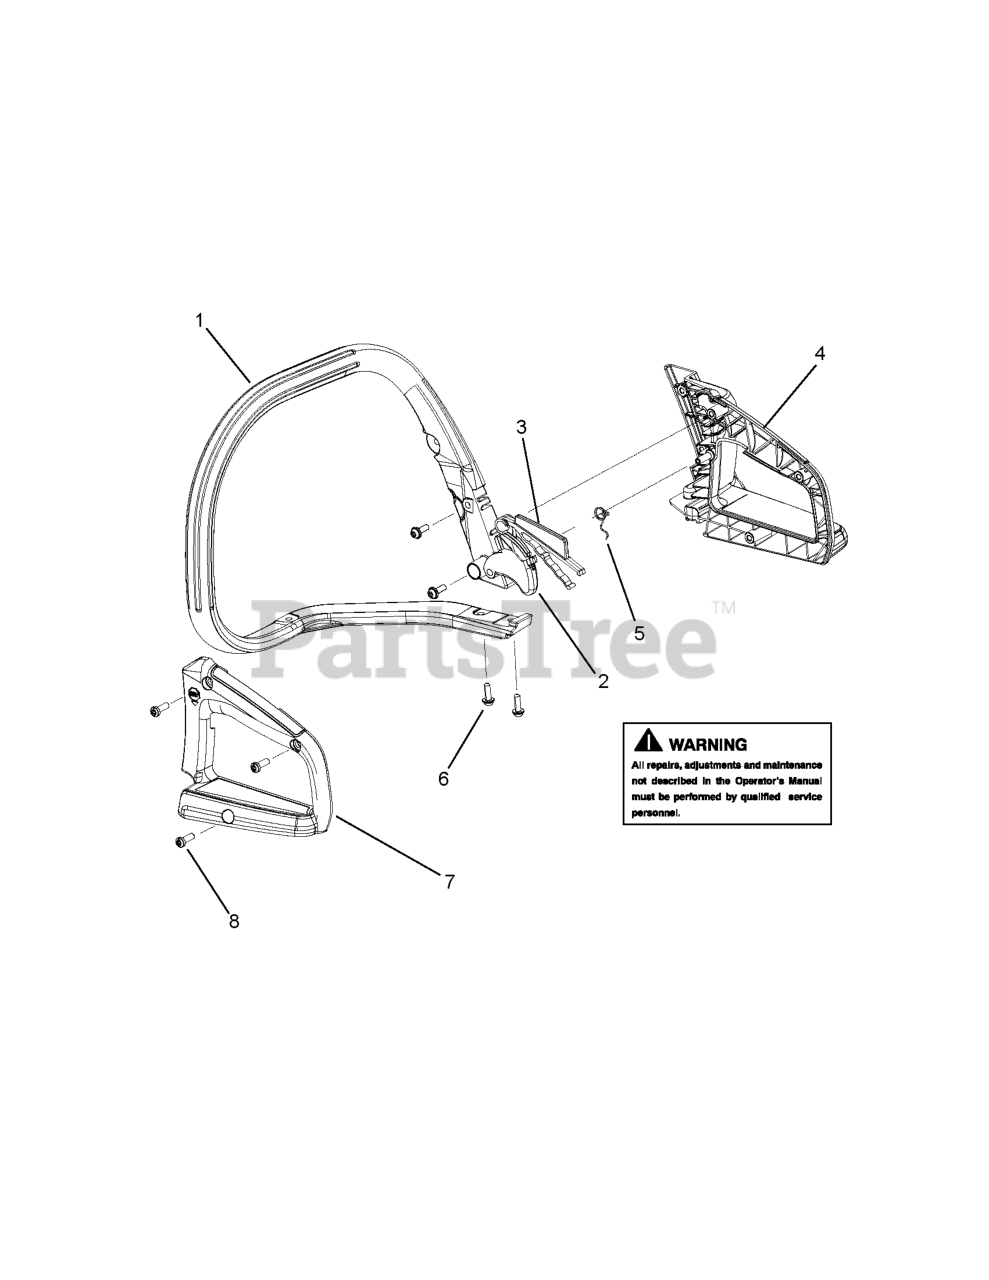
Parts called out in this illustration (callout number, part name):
1	HANDLE FRONT
2	TRIGGER
3	THROTTLE LOCKOUT
3	LOCKOUT THROTTLE YELLOW
4	HANDLE REAR
5	SPRING TRIGGER
6	SCREW,FRONT HBAR 36/41
7	HANDLE REAR COVER
8	Screw-Throttle Hsg.
